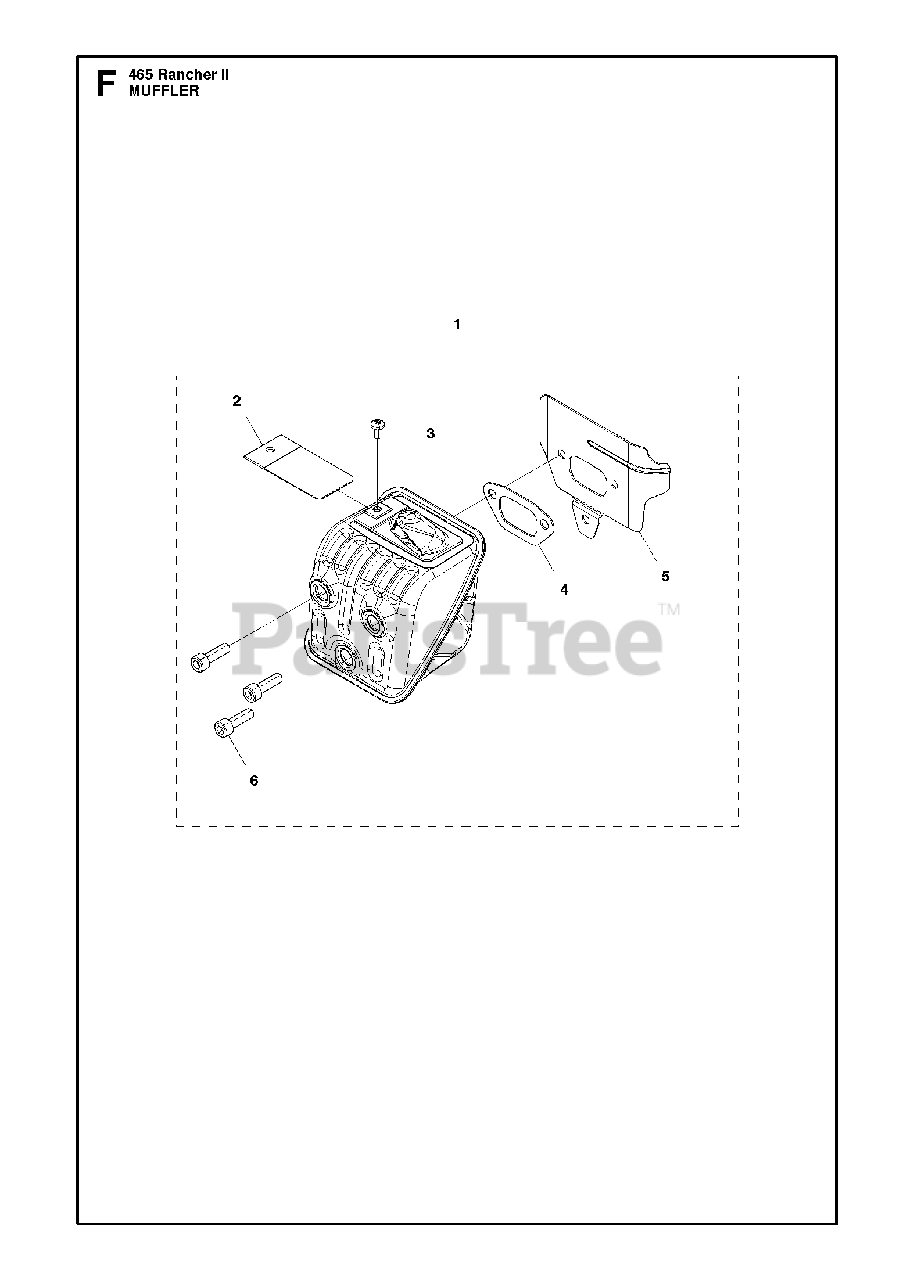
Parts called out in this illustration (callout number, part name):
1	MUFFLER KIT
2	SPARK ARRESTOR SCREEN
3	SCREW
4	GASKET
5	HEAT DEFLECTOR
6	SCREW MC6S 6X20
